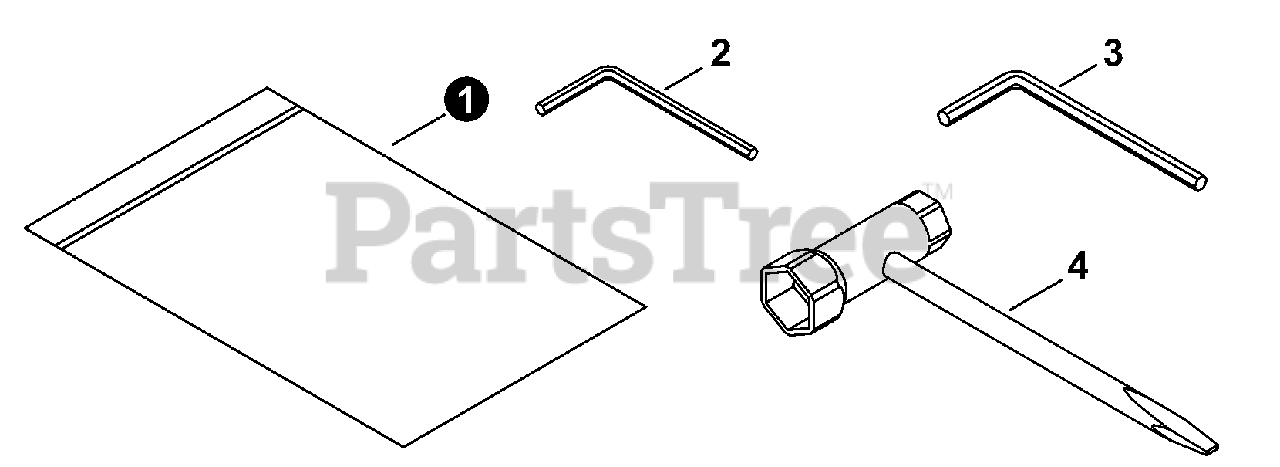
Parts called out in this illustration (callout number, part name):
1	BAG, TOOL
2	WRENCH, ALLEN 4MM
3	WRENCH, ALLEN 5MM
4	T-WRENCH 17×19mm
